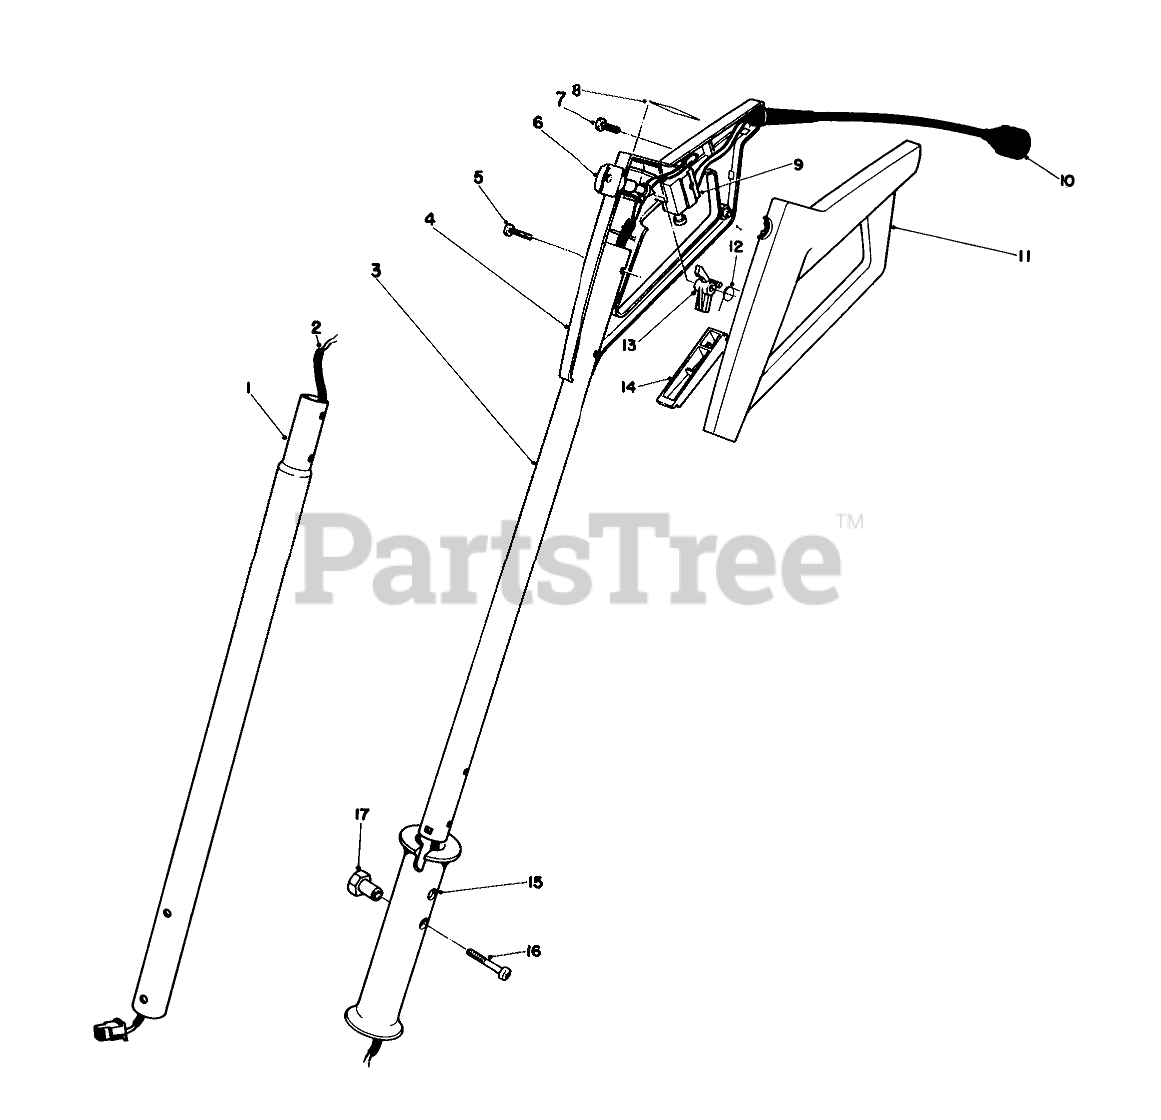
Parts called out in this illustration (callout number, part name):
1	LOWER TUBE, P. SHOVEL
2	Wire Harness
3	Tube-Upper Handle
4	Grip-Control R.H.
5	Screw
7	SCREW-PPH
8	UL GRIP DECAL
9	SWITCH-STARTER
10	Cord-Supply
11	Grip-Control L.H.
12	TORSION SPRING
13	LOCKOUT
14	SWITCH BAR,POWER SHOVEL
15	Grip-Handle
16	SPEC PAN HD SCREW
17	SPECIAL HEX NUT
